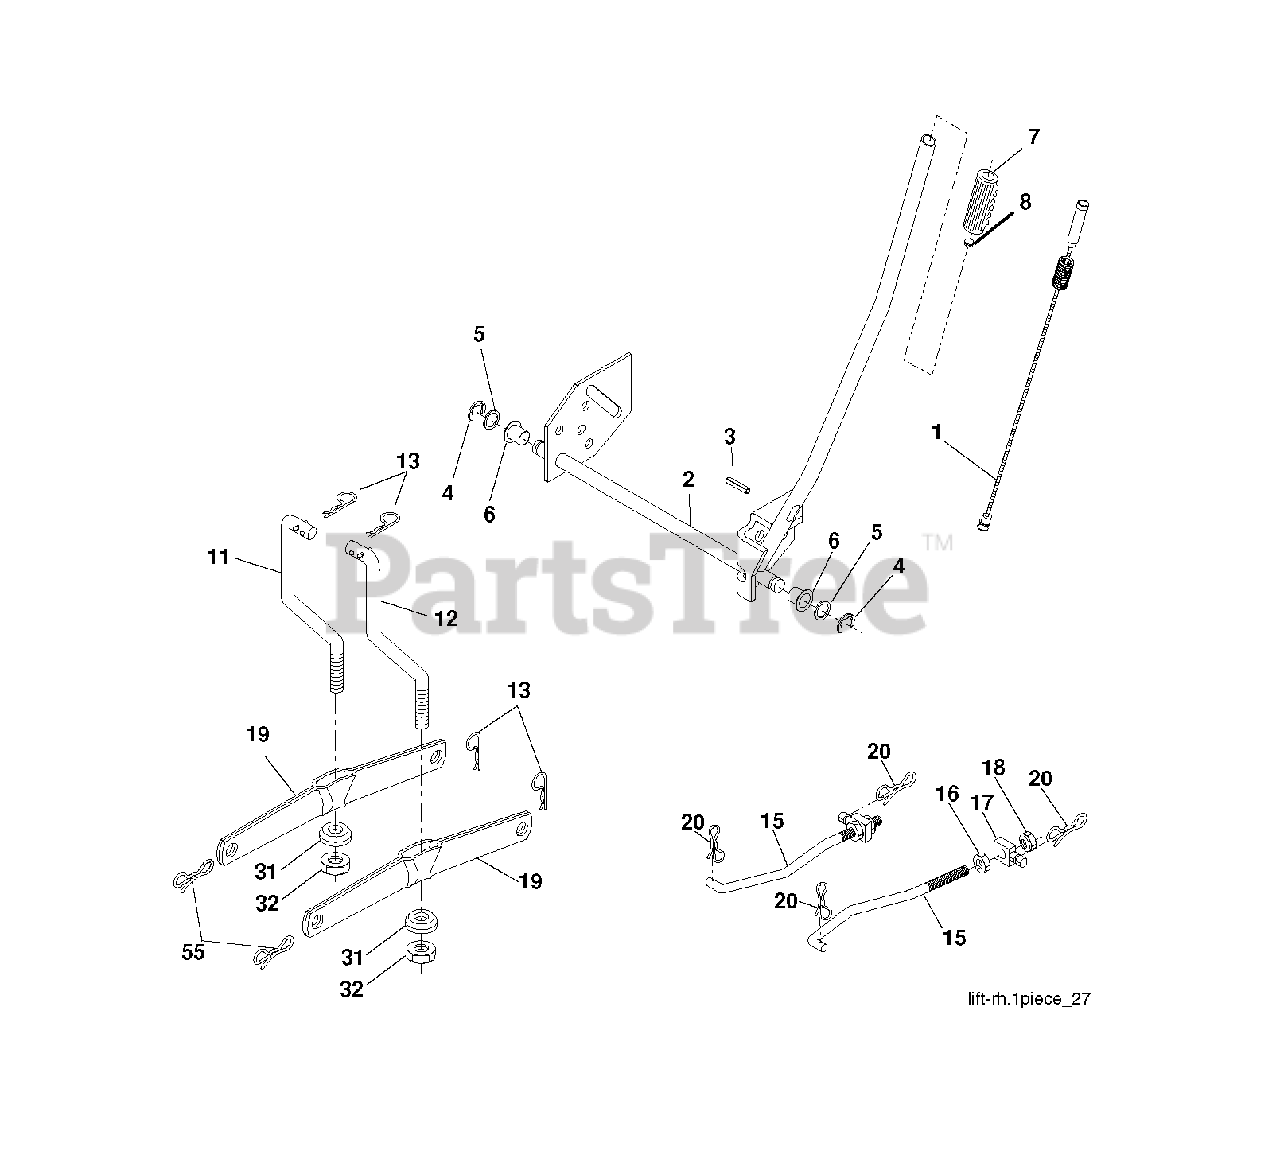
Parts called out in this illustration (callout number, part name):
1	PLUNGER.ASM.LIFT.LVR.B*SUBS/2*
2	SHAFT.ASM.LIFT.YT
3	Groove Pin, 5/16
4	RETAINING RING LT
6	BEARING.NYLON
7	GRIP
8	PLUNGER BUT KIT
11	LINK LIFT LH
12	LINK LIFT RH
13	RETAINER-SPRNG RB
15	LINK.SUSPENSION.FRONT
16	NUT
18	NUT
19	ARM.REAR.SUSPENSION
20	PIN.COTTER.7/16.BOW TI
31	BEARING.PIVOT.LIFT
32	NUT CROWNLOCK 3/8-24
55	PIN.COTTER.5/16.BOW TI
